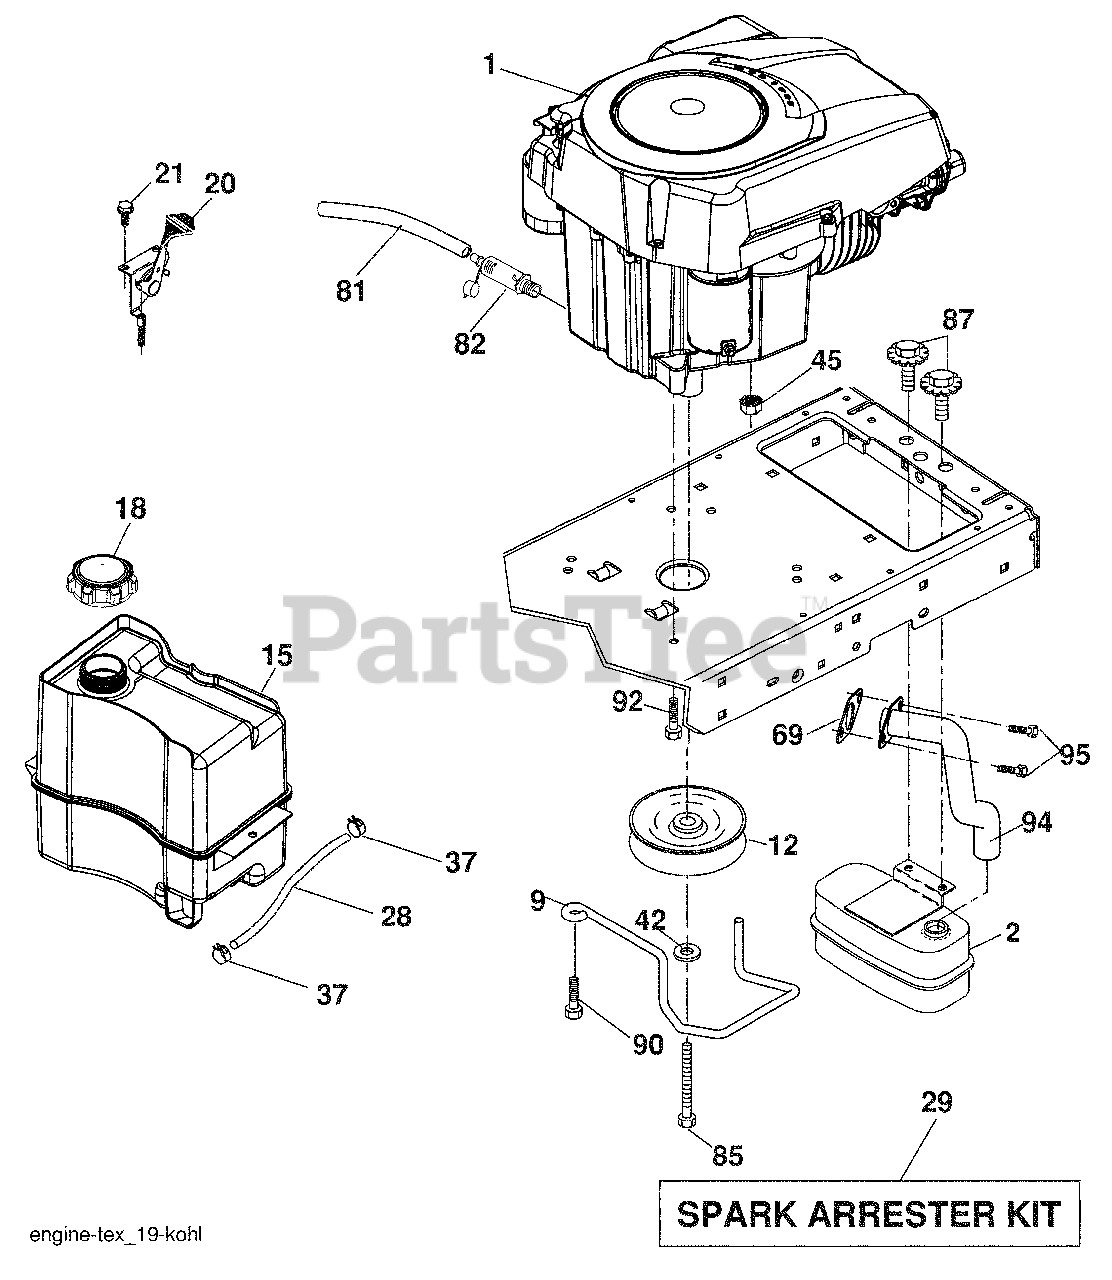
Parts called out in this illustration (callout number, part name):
9	Keeper Belt Engine
12	Pulley Engine
15	Tank Fuel
18	Cap Asm
20	Control Throttle
21	Screw 10 x 3/4 Single Lead Hex
28	Fuel Line
29	Spark Arrester Kit
37	Clamp Hose
42	Washer Lock 7/16
45	Nut Keps Hex 1/4-20 unc
81	Tube Drain Oil Easy
82	Plug Drain Oil
85	Bolt Hex 7/16-20 x 4 x Gr. 5-1.5 Thr
87	Bolt 5/16-18 UNC x 3/4 w/Sems
90	Screw 3/8-16 x 1
92	Screw 3/8-16 x 1
94	Tube Exhaust
95	Screw Socket Hd. 5/16-18 x .75
